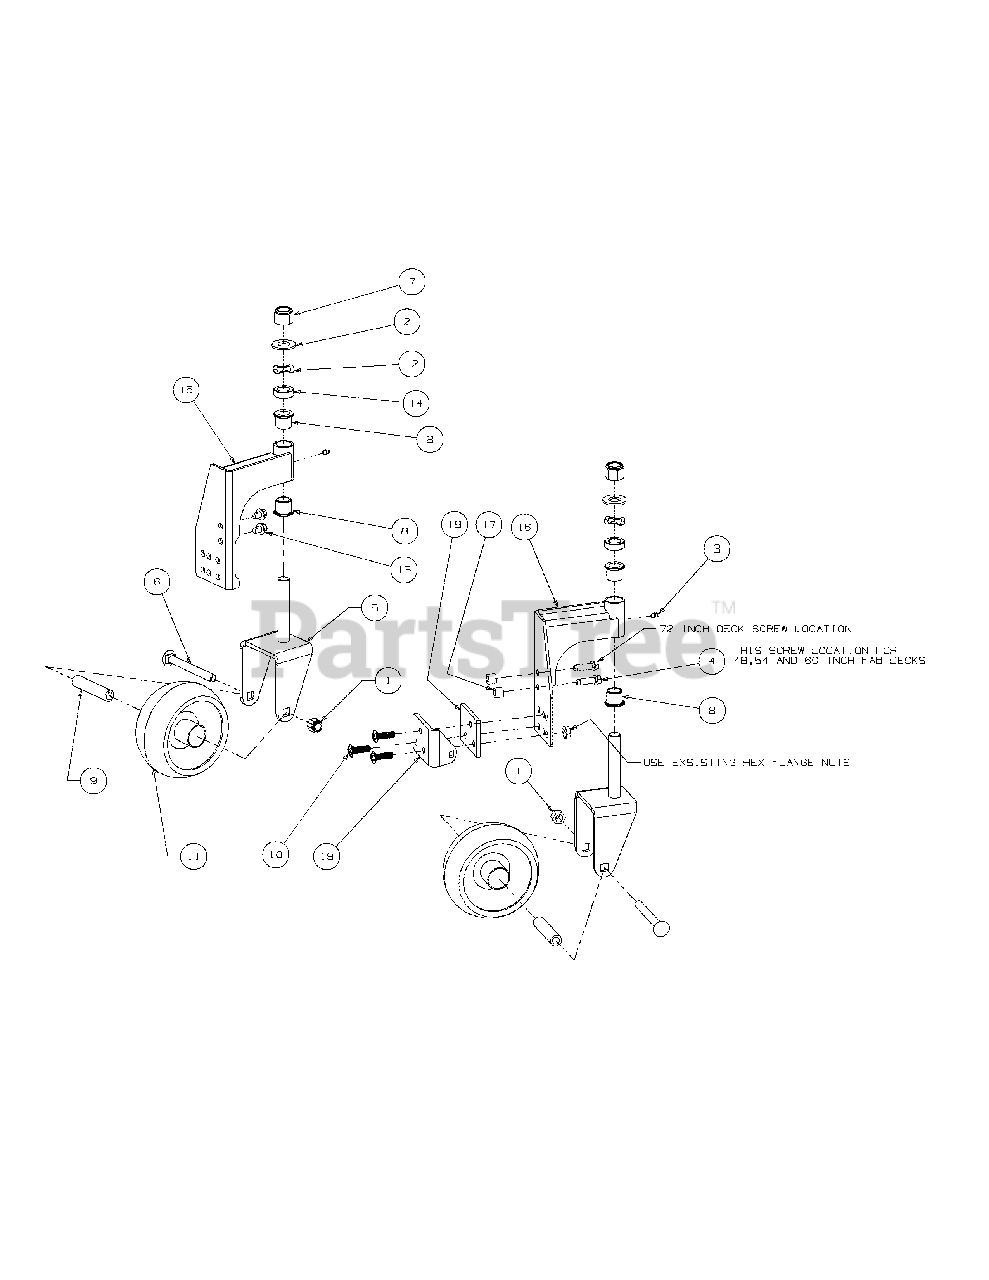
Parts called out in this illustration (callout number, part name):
1	Nylock Nut:1/2-13
2	Flat Washer, .750 x 1.50 x .120
3	Grease Fitting, 1/4-28 x 3/16
4	Self Tapping Screw, 3/8-16 x 1.250
6	Carriage Screw, 1/2-13 x 4.50
7	Nut, 3/4-10, Hex Lock
8	Flange Bearing, .754 ID x 1.00 OD x .925
9	Axle, Caster Wheel
10	Carriage Screw, 3/8-16 x 1.25
11	Wheel Assembly, 6.25 x 3.00-4
12	Wave Washer, 1.38 OD x .88 ID x .02
13	Self Tapping Screw, 3/8-16 x .500
14	Spacer, .76 ID x 1.25 OD x .44
15	Castor Bracket Assembly, LH
16	Castor Bracket Assembly, RH
17	Spacer, .385 ID x .625 OD x .50
19	Front Anti Scalp Bracket
